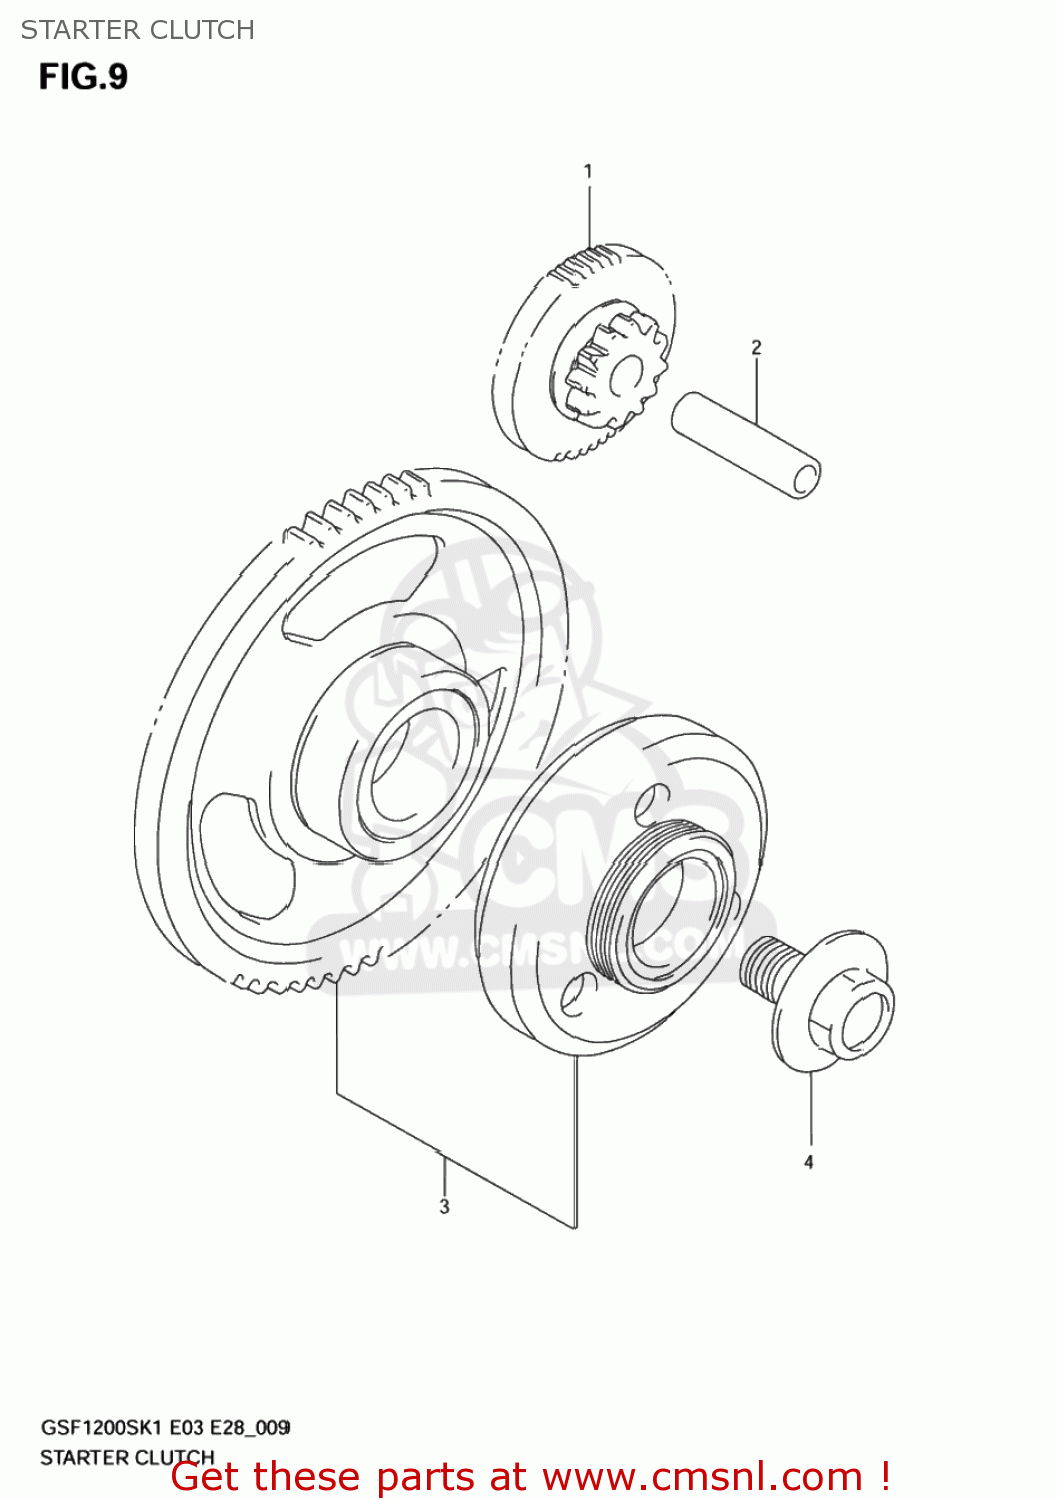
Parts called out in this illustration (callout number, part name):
1	GEAR,STARTER IDLE(NT:12,53)
2	PIN(7X11X42)
3	CLUTCH SET,STARTER
4	BOLT(14X21)
